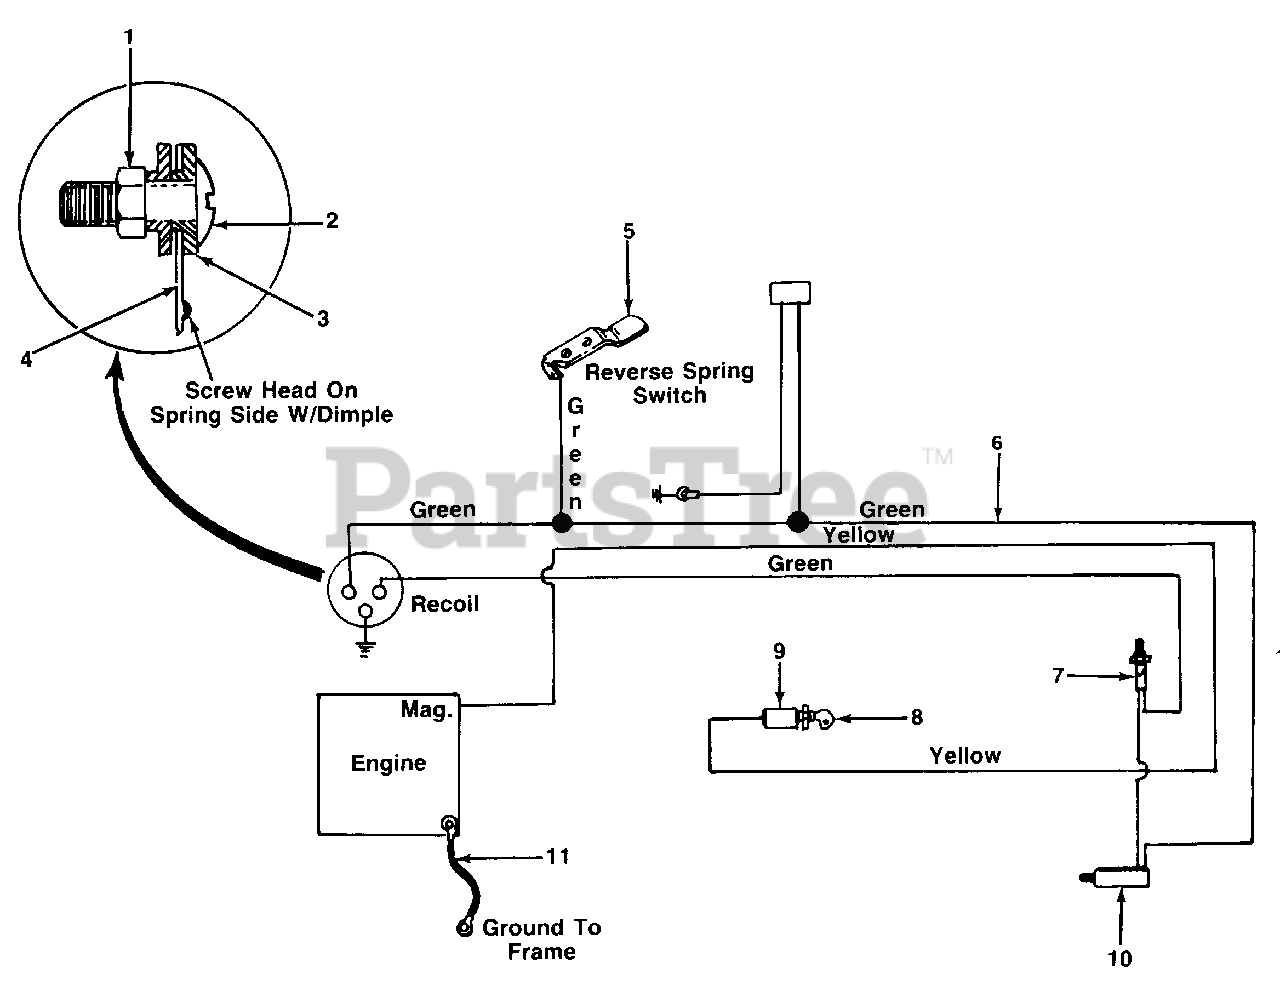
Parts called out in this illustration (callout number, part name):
1	Hex Nut #10-24 Thd.
2	Truss Mach. Scr. #10-24 x .62" Lg.
3	Fiber Washer
4	Switch Spring-Recoil
5	Spring Switch-Reverse
6	Wire Harness
7	Safety Switch-Red N.C.-Clutch
8	Ignition Key
9	Ignition Switch
10	Safety Switch-P.T.O.
11	Ground Wire
